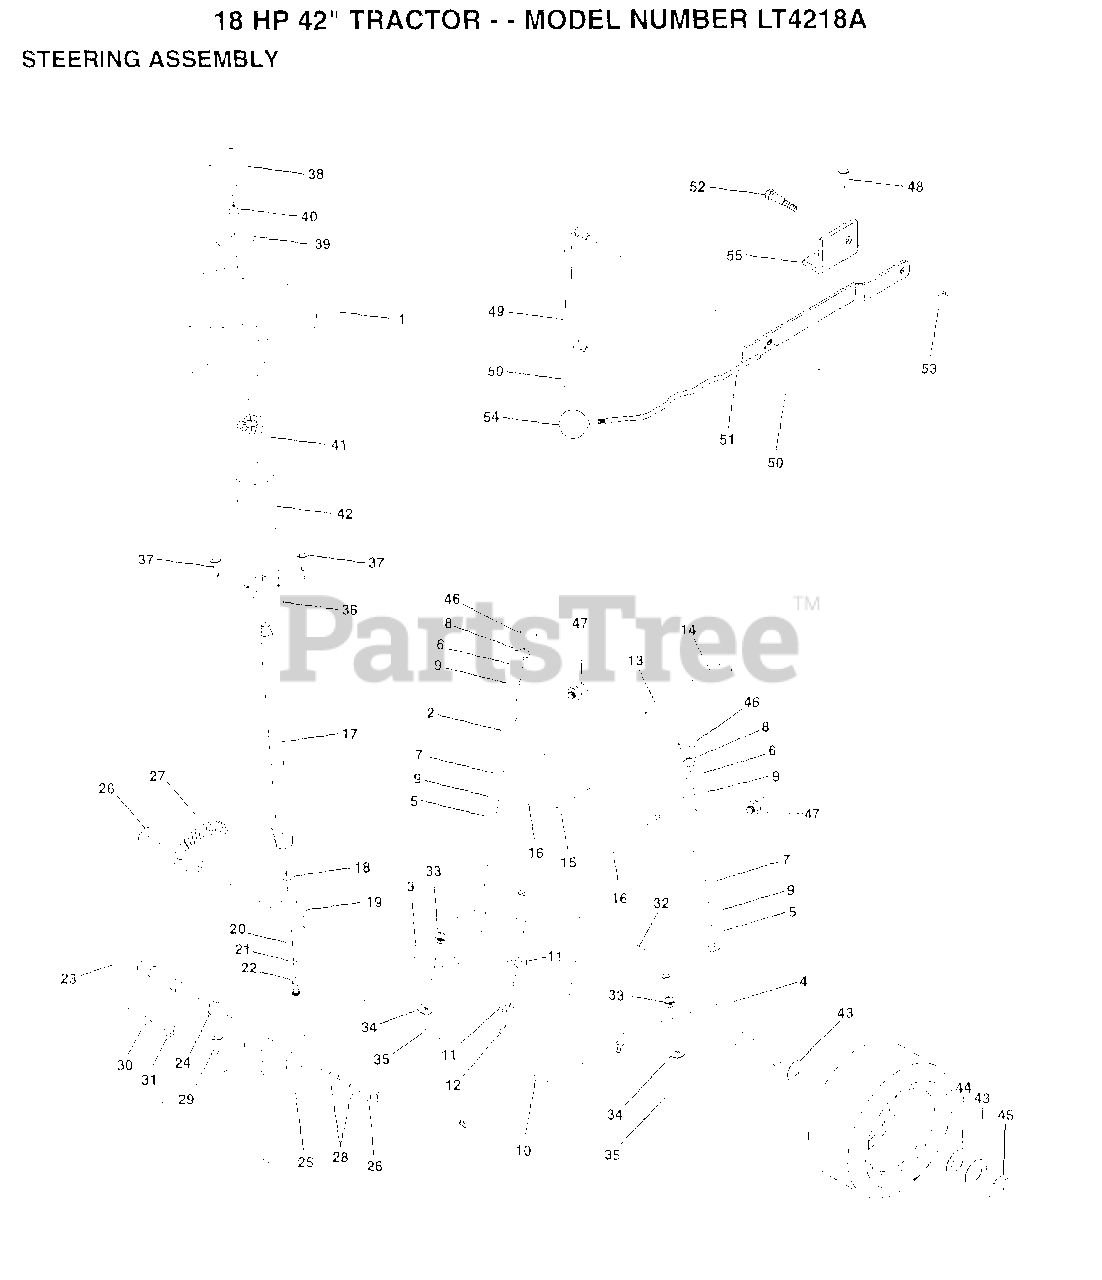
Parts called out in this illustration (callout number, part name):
2	AXLE ASM FRONT
3	SPINDLE LH
4	SPINDLE RH
5	WASHER .T
6	WASHER
7	WASHER
8	RING
9	COL. SRTG. BEAR.
11	LOCKWASHER
13	BEARING
14	BOLT HEX 5/8-11
15	"NUT-LOC,FLANGE LT"
16	AXLE PIN
17	SHAFT&GEAR STR T
18	THRUST WASHER
19	SUPPORT.SHAFT
21	LOCKWASHER
22	"SCREW,SPECIAL"
24	NYLINER T
25	"BRKT,STEERING"
26	RING
27	GEAR SECTOR
28	WASHER .T
29	SCREW
30	LOCKWASHER
32	TIE ROD
33	BUSHING LINK DRAG BLK
34	WASHER
35	COTTER PIN
38	INSERT, CAP
39	WASHER
41	ADAPTER LT
43	WASHER
44	WASHER
45	RING
46	CAP
47	ZERK M
48	SCREW
49	LINK CLTCH W/NUTS
50	COTTER PIN
51	LEVER ASSY T
52	"BOLT, SHOULDER LT"
54	KNOB T (1/2-HOLE)
55	BRKT.PVT.MAN.LVR.
